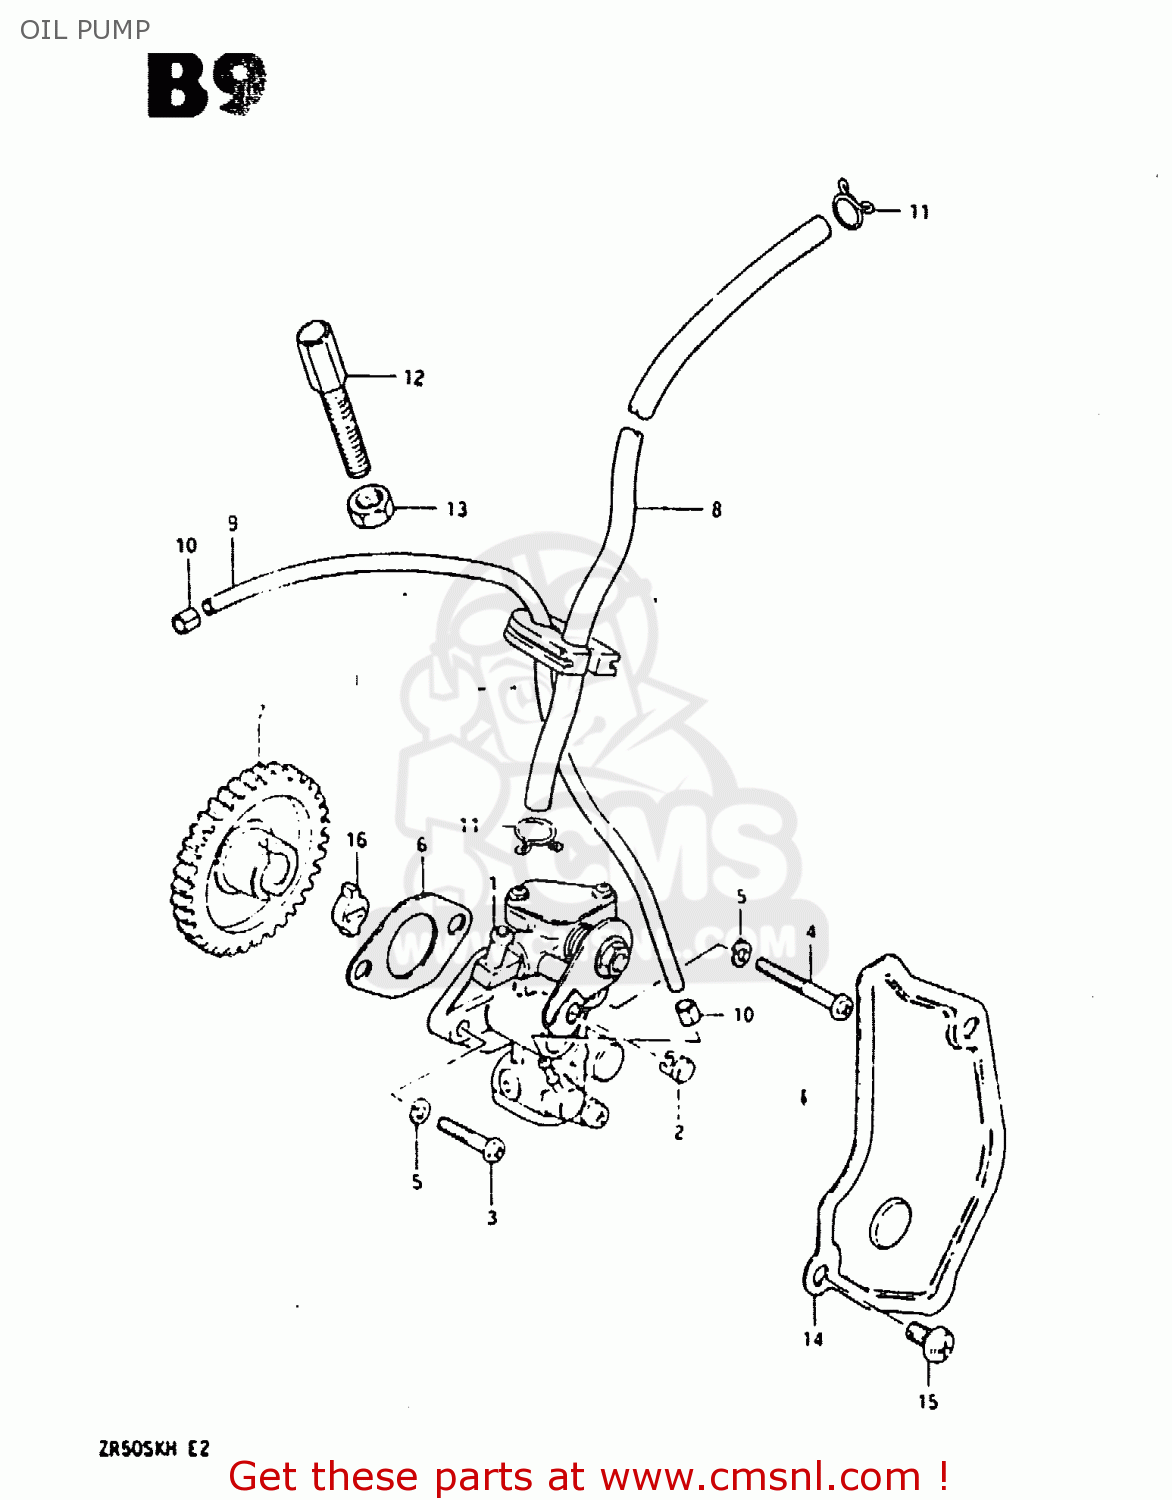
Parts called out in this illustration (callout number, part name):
1	PUMP ASSY,OIL
2	TERMINAL,CABLE
3	SCREW
4	SCREW
5	LOCK WASHER
6	GASKET,OIL PUMP (NAS)
7	GEAR,OIL PUMP DRIVE
8	HOSE
9	HOSE,NO.2
10	CLIP
11	CLIP
12	BOLT
13	NUT
14	CAP,OIL PUMP INSPECTION
15	SCREW
16	PIECE,OIL PUMP DRIVE
